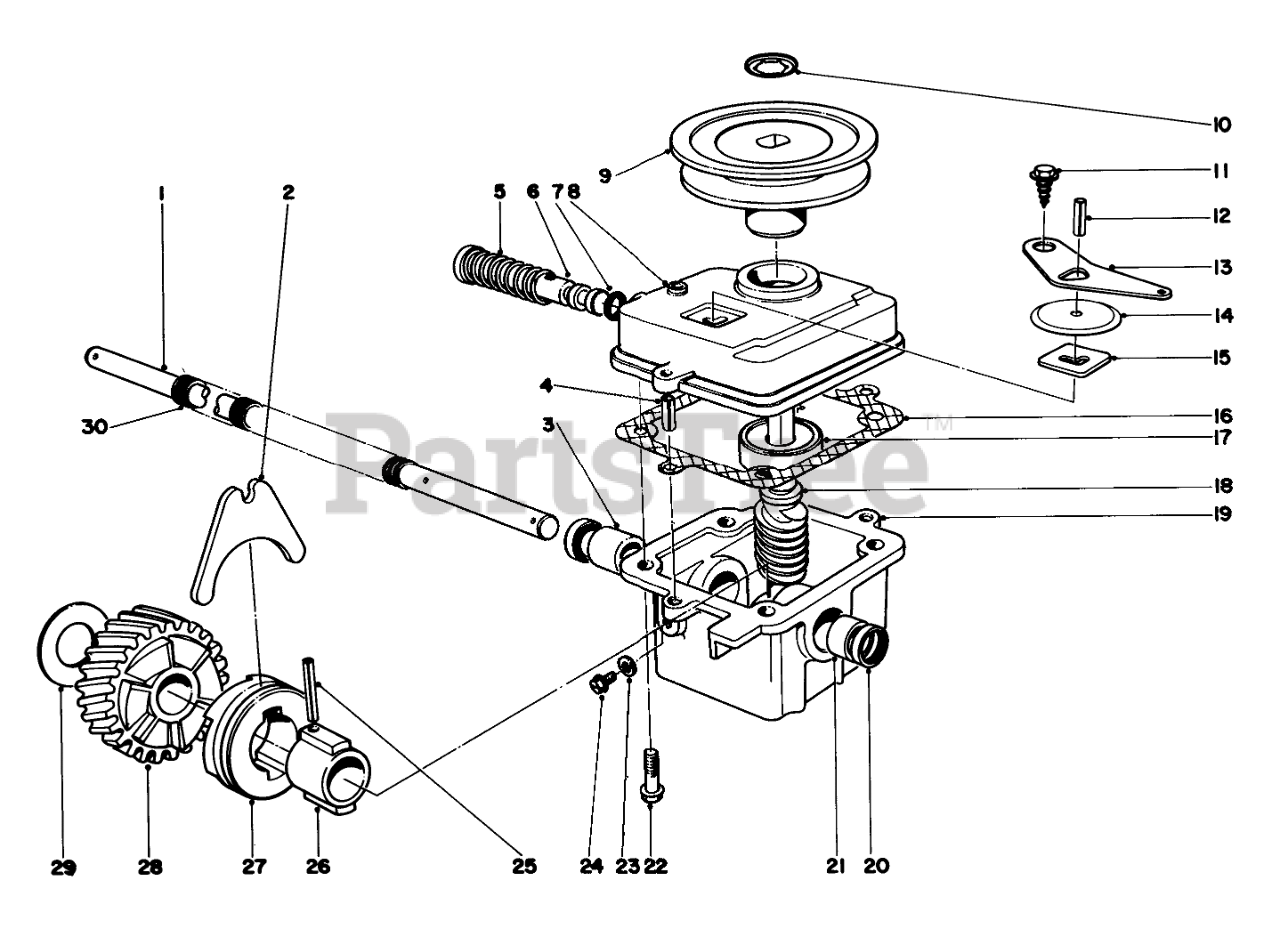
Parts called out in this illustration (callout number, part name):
1	DRIVE SHAFT (SERVCE)
2	SHIFTER FORK
3	Bushing
4	3/16 X 1/2 ROLL PIN
5	SPRING
6	SHIFTER ROD
7	O-RING
8	Case-Upper
9	PULLEY
10	PUSH-ON 93-3236
11	Screw
12	PIN-ROLL
13	SHIFTER ARM
14	TRANS DUST COVER
15	LATCH PLATE
16	GASKET
17	Bearing
18	Worm Shaft/Gear (Incl. Ref. #28)
19	Gear Case (Incl . Ref. #3, 20 & 21)
20	Seal
21	Bushing
22	Screw
23	FILL PLUG GASKET
24	NYLON SCREW
25	COIL PIN
26	SLEEVE
27	CLUTCH JAW
28	Helical Gear
29	THRUST WASHER
30	DRIVE SHAFT COVER
